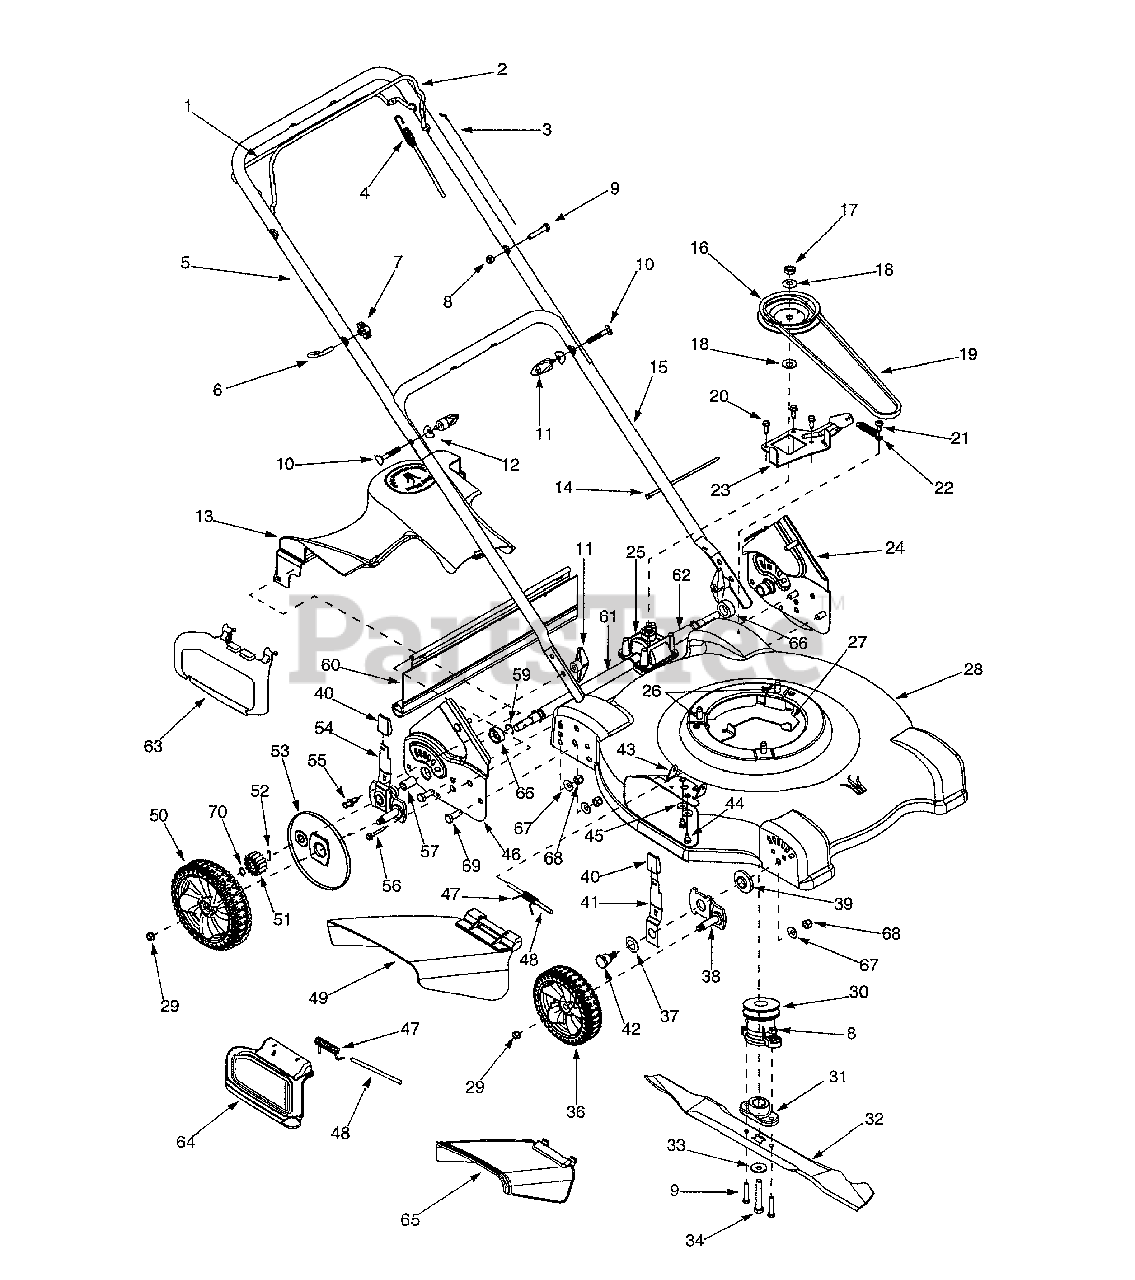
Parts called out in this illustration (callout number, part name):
1	Drive Control Handle
3	Blade Control Cable - B&S
4	Drive Control Cable
6	Eye Bolt
7	Wing Nut 1/4-20
8	Hex Lock Nut 1/4-20
9	Hex Cap Screw 1 /4-20 x 1.5
10	Carriage Bolt 5/16-18 x 2.0
11	Wing Nut 5/16-18
12	Shoulder Washer .320 ID x .93 OD
13	Transmission Cover
14	Cable Tie
16	Transmission Pulley
17	Jam Nut 7/16-20
18	Bell Washer .45 ID x 1.00 OD
19	V-Belt
20	Hex Washer Screw 1/4-20 x .75
21	Shoulder Screw .375 x .25
22	Extension Spring
23	Transmission Belt Bracket
26	Hex Washer Screw 3/8-16 x 1.0
27	Engine Belt Keeper Bracket
30	Engine Pulley
31	Blade Adapter
32	Blade 22"
33	Bell Washer .396 ID x 1.140 OD
34	Hex Cap Screw 3/8-24 x 2.5
36	Front Wheel 7 x 1.8
37	Bell Washer .401 ID x .870 OD
38	Pivot Arm Assembly
39	Height Adjuster Bearing
40	Height Knob
41	Spring Lever
42	Shoulder Screw 3/8-16
43	Chute Hinge
44	Hex Washer Screw 1/4-20 x .50
45	Bell Washer .265 ID x .75 OD
48	Hinge Pin
49	Side Discharge Assembly
50	Rear Wheel 8 x 1.8
51	Spur Gear 14T RH
52	Pin
53	Wheel Cover
54	Spring Lever Assembly - RH
55	Plastic Rivet
56	Screw 1/4-20
57	Sleeve Bearing
59	Retainer Ring
60	Trail Shield
61	Sleeve Spacer .550 ID x 9.0 OD
62	Sleeve Spacer .550 ID x 2.44 OD
63	Snap Mulching Plug
64	Mulching Baffle
65	Snap Discharge Chute
66	Bearing Spacer
67	Washer Spacer .401 ID x .870 OD
68	Hex Lock Nut 3/8-16
69	Hex Cap Screw 3/8-16 x 1.0
70	Snap Ring .500
